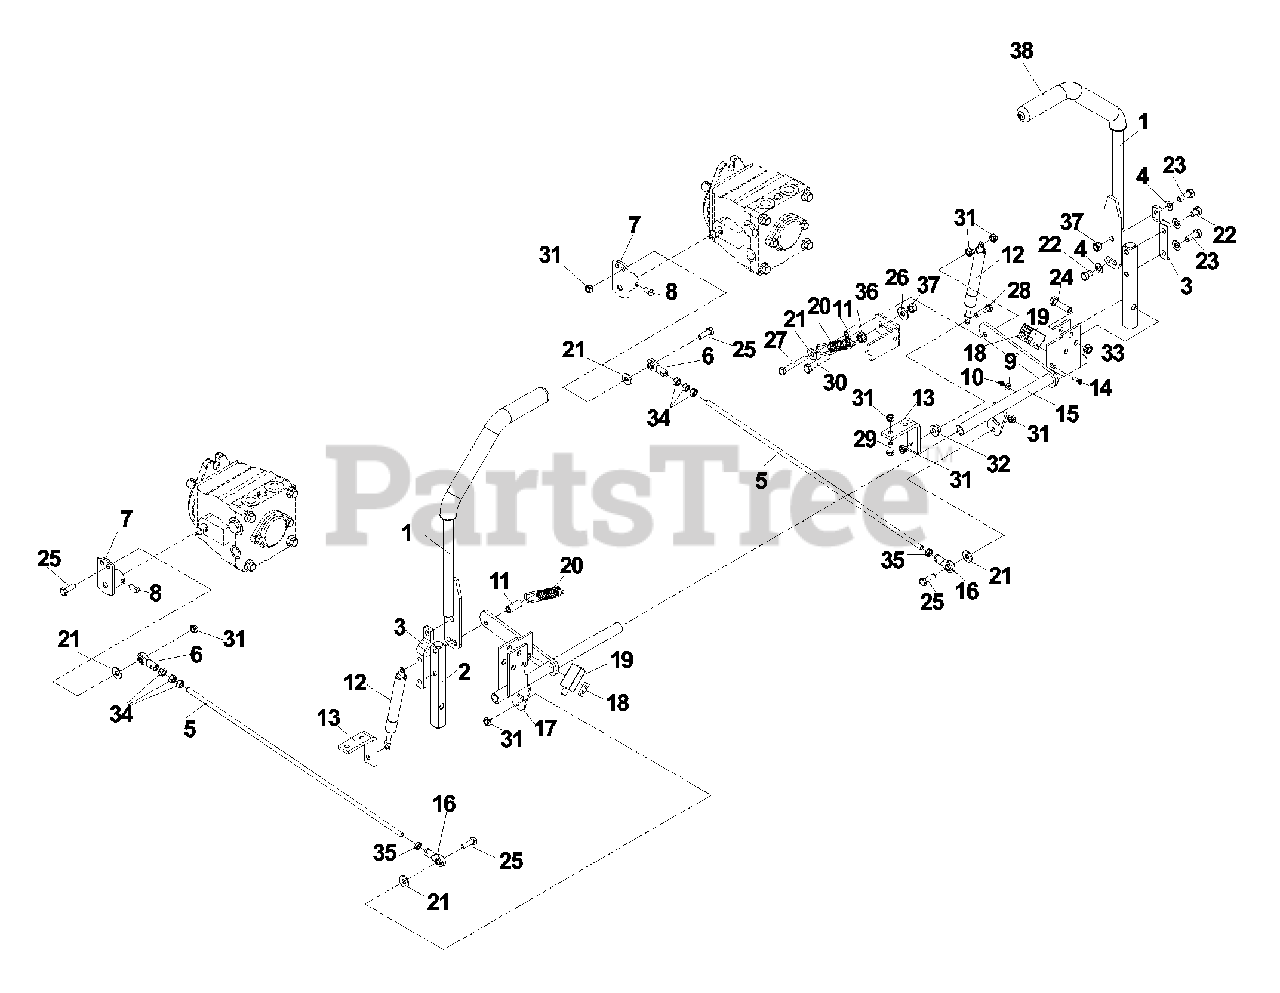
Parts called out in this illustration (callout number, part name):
2	Arm, control shaft
3	Control lever extension
4	Washer, 3/8, spring
5	Pump linkage bar
6	Ball end, right
7	Pump lever
8	Setscrew, 5/16-18 sq. x 5/8, cone pt.
10	Zerk
13	Bracket, L
14	Screw, #10-24 x 5/8
15	Control, left
16	Ball end, left
17	Control, right
18	Tapped plate
20	Detent spring, rev.
21	Washer, 5/16
22	Bolt, 3/8-16 x 1/2
23	Bolt, 3/8-16 x 1
24	Bolt, 3/8-16 x 1 1/2
25	Bolt, 5/16-18 x 1
26	Washer, 3/8
27	Bolt, 5/16-18 x 2 1/4, tap
28	Bolt, 5/1618 x 1 1/4
29	Bolt, 5/16-18 x 3/4
30	Bolt, 3/8-16 x 2
31	Nut, 5/16-18, centerlock
32	Nut, 5/16-18, serrated washer
33	Nut, 3/8-16, centerlock
34	Nut, 5/16-24
35	Nut, 5/16-24, jam, LH
36	Nut, 3/8-16
37	Nut, 3/8-16, nyloc
